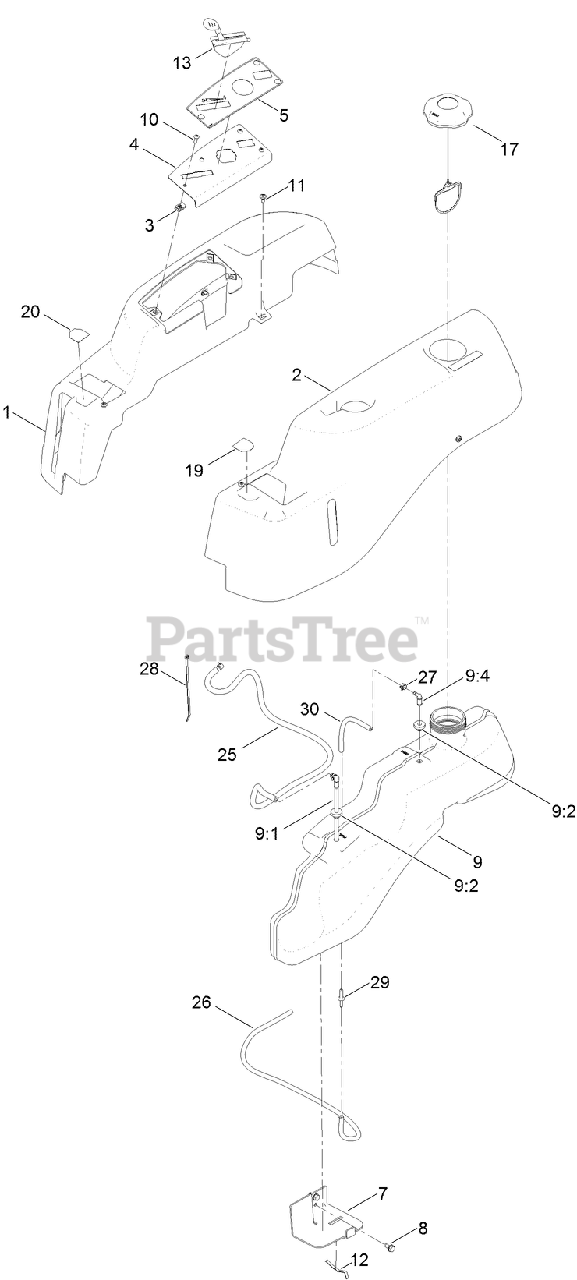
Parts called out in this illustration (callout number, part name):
1	POD-RH
4	PLATE-CONTROL
5	DECAL-PANEL, CONTROL
7	SUPPORT-TANK, FRONT
8	SCREW-HWHTF
9	FUEL TANK ASM
9:1	CONNECTOR-ELBOW, 90 DEG
9:2	BUSHING
9:4	FITTING-PLASTIC
10	SCREW-PRH
11	SCREW-SHOULDER
12	SPRING
13	CABLE-THROTTLE AND CHOKE
19	DECAL-LEVER, CONTROL (LH)
20	DECAL-LEVER, CONTROL (RH)
25	HOSE-FUEL
26	HOSE-FUEL
27	CLAMP-HOSE
28	TIE-CABLE
29	ADAPTOR-ORIFICE
30	HOSE-FUEL
